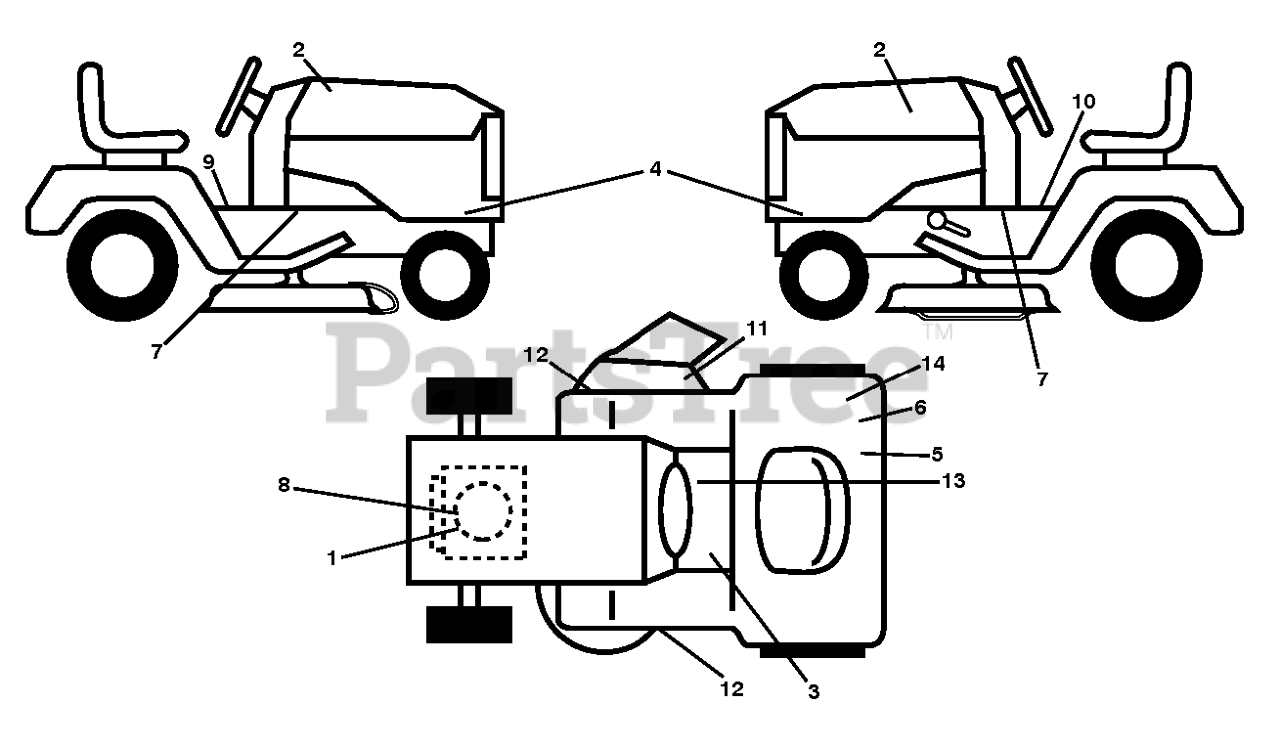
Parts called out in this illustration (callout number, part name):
1	DECAL
2	DECAL.HOOD.LOGO.ORANGE.HUSQVAR
3	DECAL
5	DECAL
6	DECAL
9	DECAL BTRY SYMBOLS
10	LABEL
11	DECAL.WARN.DFLECT/CTFINGR.SRD
12	Decal, Mower V-Belt Schematic
13	DECAL PARK BRAKE
14	DECAL 80 DBA
